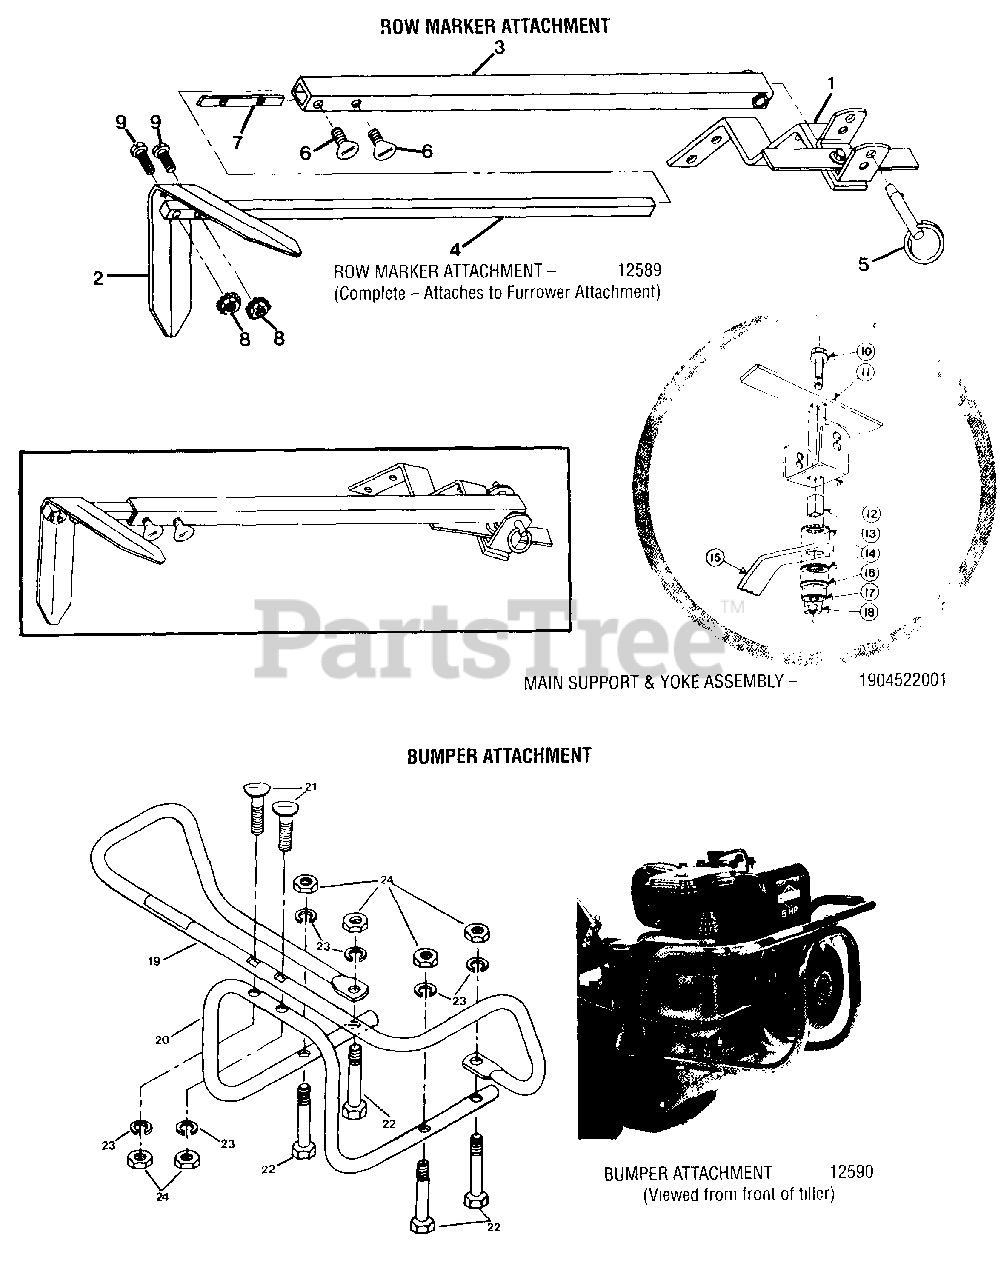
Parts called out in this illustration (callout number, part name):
1	Main Support & Yoke Assy complete
2	Marker Blade-blade only
3	Marker Arm-main arm
4	Marker Arm-extension arm with stop pin
5	Hitch Pin
6	Thumbscrew-1/4-20 x 1/2,
7	Nut Bar
8	Nut-hex, 10-24 w/attached start washers
9	Screw-round hd,10-24 x 1
10	Screw-hex flanged locking, 3/8-16 x 1-1/2
11	Stop Bar
12	Yoke
13	Tube Key-square
14	Washer-friction
15	Main Support
16	Washer-square hole
17	Washer-disc spring
18	Nut-hex 3/8-16
19	Bumper-top section
20	Bumper-bottom section
21	Bolt-curved head, 5/16-18 x 2
22	Bolt-hex hd, 5/16-18 x 2-1/2,
23	Lockwasher-5/16,
24	Nut-hex, 5/16-18,
